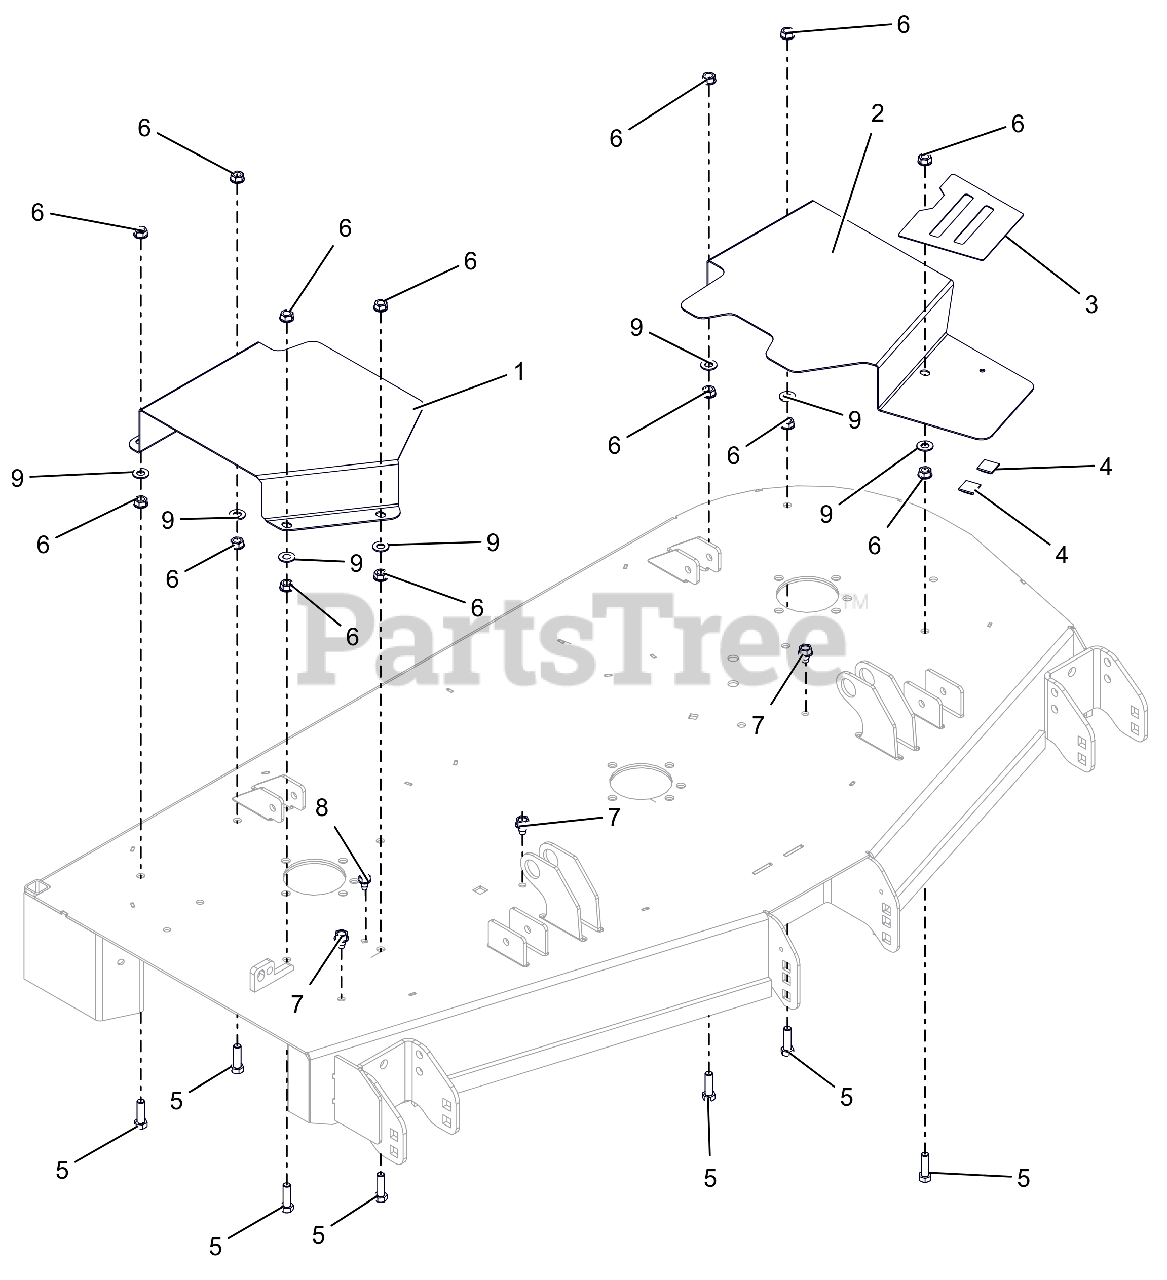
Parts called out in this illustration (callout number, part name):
1	COVER, BELT 52" & 60" RIGHT
2	COVER, BELT 52" LEFT
3	GRIP, TAPE 52-60 BELT COVER
5	BLT, HEX .38-16X1.25 G5 ZCC
6	NUT, SPNLK-FLG .38-16 G5 ZCC
7	SCR,TAP .375-16X.50 HWH TR ZCC
8	SCR,TAP .312-18X.50 HWH TR ZCC
9	WSHR,FLT .406X.812X.065 ZCC
